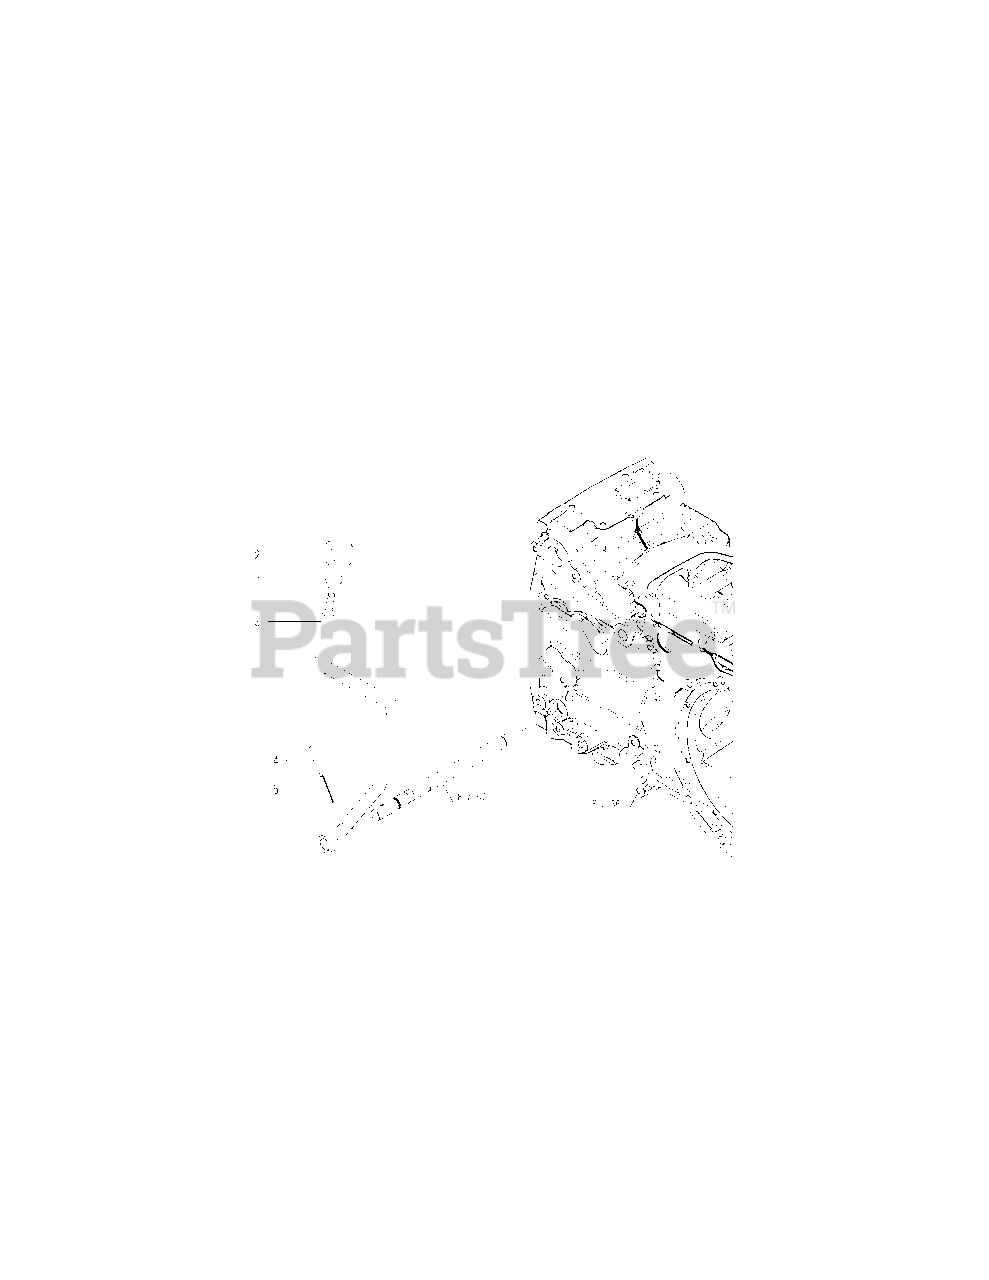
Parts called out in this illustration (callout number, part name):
1	NUT W/WASHER 10
3	CHANGE ARM, FRONT
4	SPRING PIN 3.5X40
5	SPRING PIN 6X40
